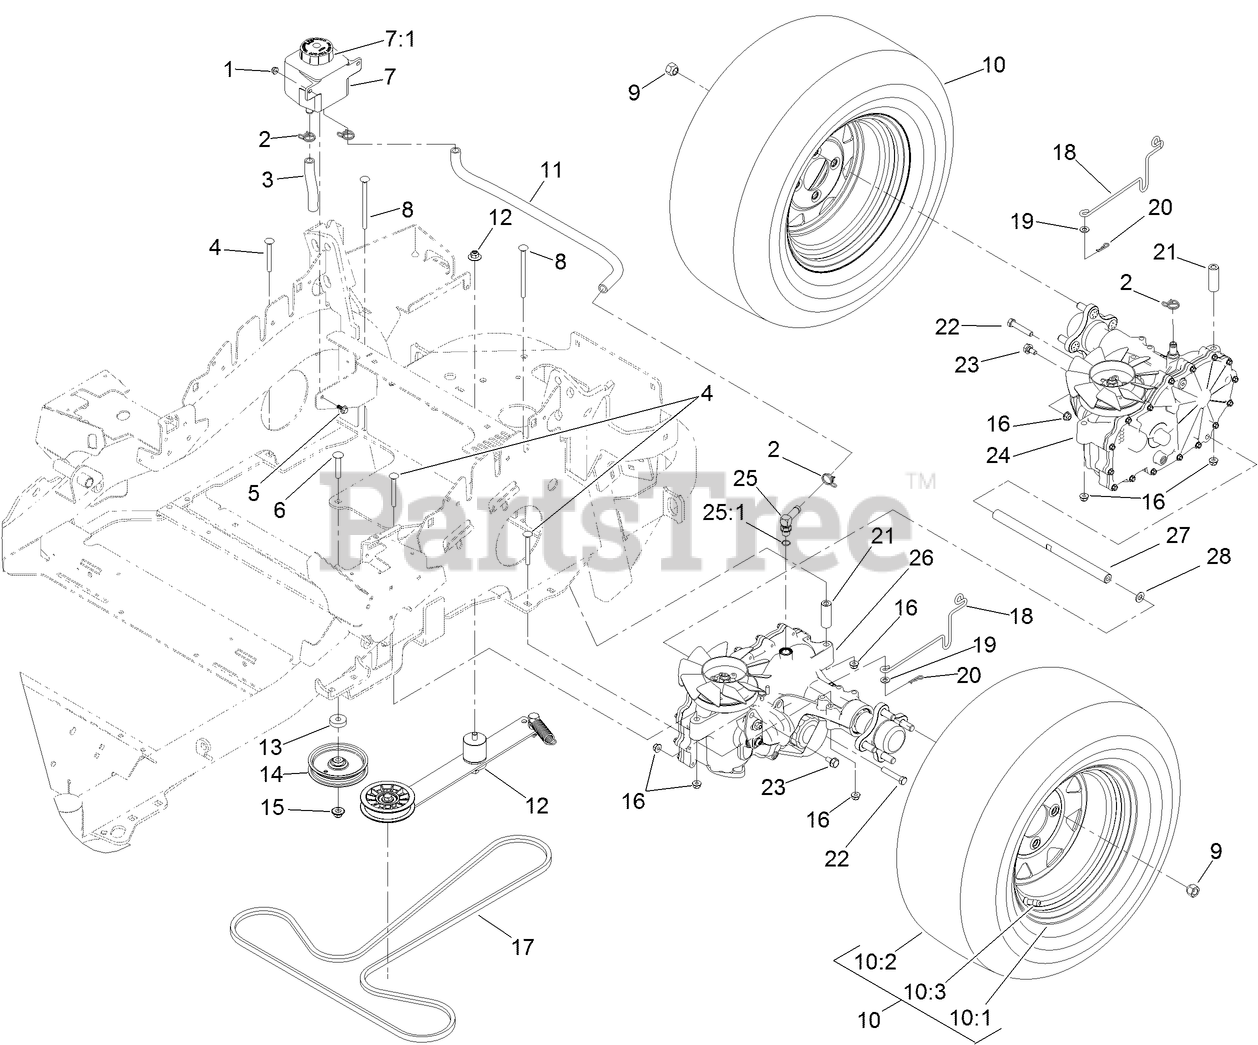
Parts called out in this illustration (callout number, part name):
1	NUT-HF
2	CLAMP-HOSE
3	HOSE-HYD
4	SCREW-CARR
5	SCREW-HHF
6	BOLT-CARRIAGE
7	TANK-HYD
7:1	CAP-RESERVOIR, HYD
8	SCREW-CARR
9	NUT-LUG
10	WHEEL AND TIRE ASM
10:2	TIRE
10:3	STEM-VALVE
11	HOSE-HYD
12	HYDRO IDLER ARM ASM
13	Spacer
14	PULLEY-IDLER
15	NUT-FLANGE, NI
16	NUT-HF, NI
17	BELT-V
18	ROD-BYPASS
19	WASHER-PLAIN
20	PIN-COTTER
21	SPACER-HYDRO
22	SCREW-HH W/LOCTITE
23	BOLT-SHOULDER
24	RH TRANSAXLE ASM
25	FITTING-ELBOW, 90
25:1	O-RING
26	LH TRANSAXLE ASM
27	SHAFT-CROSS, HYDRO
28	WASHER-FLAT
